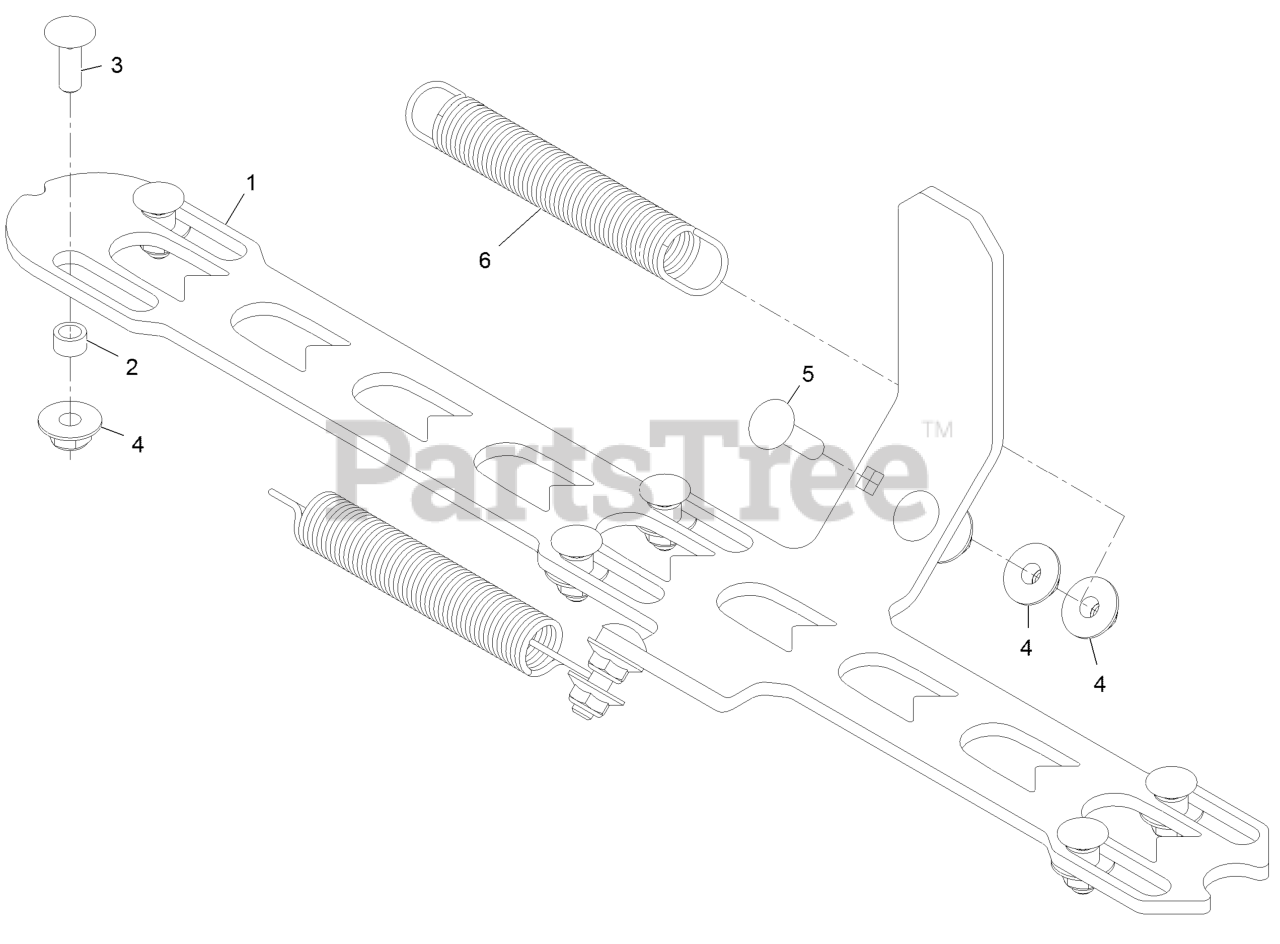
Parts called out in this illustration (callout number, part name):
1	GATE-SEED
3	BOLT-CARR
5	SCREW-CARR
6	SPRING-EXTENSION
